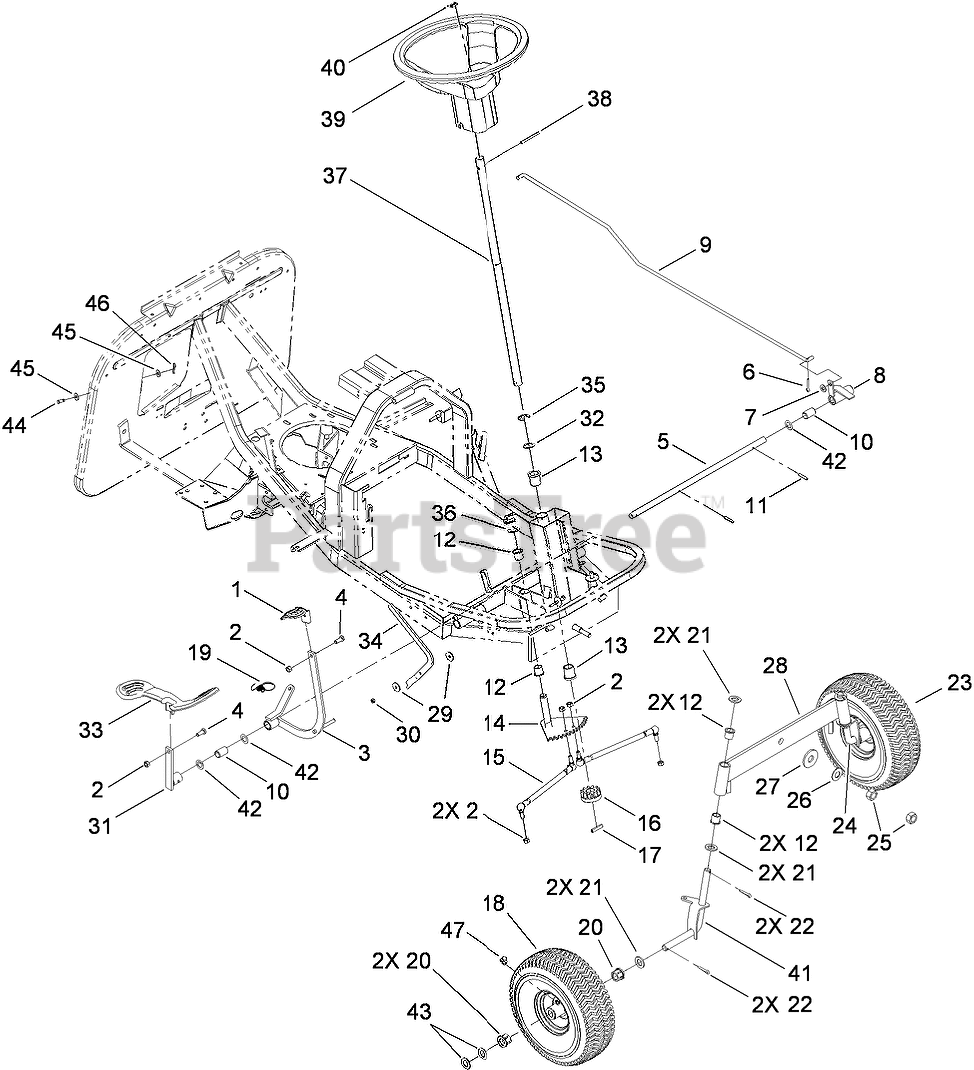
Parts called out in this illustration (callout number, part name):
1	Pedal-Brake
2	NUT-LOCK
3	LEVER-BRAKE
4	SCREW-HH
6	PIN-COTTER
7	WASHER-PLAIN
8	BUSHING-LINKAGE
9	ROD-LINKAGE
10	Bushing
11	Pin-Dowel
12	Bushing
13	Bushing
14	Rack-Steering
15	Rod-Tie
16	Gear-Steering
17	Pin-Spiral
19	SPRING-RETURN, BRAKE
20	Bushing
21	WASHER-FLAT
22	PIN-COTTER
24	AXLE-WHEEL, LH
25	NUT-HEX
26	Washer-Bell
27	Washer-Flat
28	Axle-Front
29	Washer-Flat
30	NUT-LOCK
31	Lever-Foot Pedal
32	Spacer
35	RING-RETAINING, EXT
36	RING-RETAINING, EXT
37	Shaft-Steering
38	Pin-Roll
39	WHEEL-STEERING
40	DECAL
41	AXLE-WHEEL, RH
42	Spacer
43	Washer
44	PIN-GROOVED
45	Washer-Flat
46	Pin-Hair
47	ZERK-GREASE, 90 DEG
